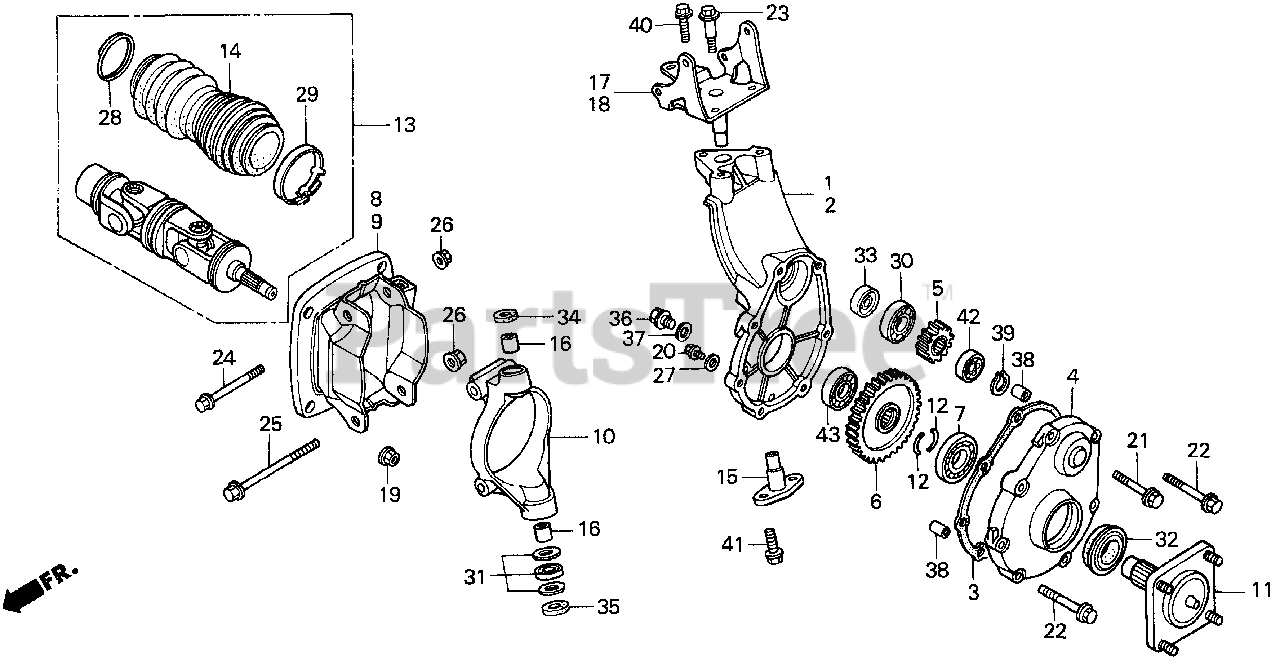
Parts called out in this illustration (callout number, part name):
1	CASE, R. RR. FINAL REDUCTION
2	CASE, L. RR. FINAL REDUCTION
3	GASKET, FINAL REDUCTION
4	COVER, FINAL REDUCTION
5	GEAR, FINAL DRIVE (12T)
6	GEAR, FINAL DRIVEN (35T)
7	BEARING, RADIAL BALL SPECIAL (6206)
8	TUBE, R. RR. AXLE
9	TUBE, L. RR. AXLE
10	HOLDER, FINAL REDUCTION CASE
11	SHAFT, AXLE
12	KEY, AXLE SHAFT LOCK
13	JOINT ASSY., RR. DRIVE
14	BOOT, RR. JOINT
15	KINGPIN (LOWER)
16	BUSH, KINGPIN
17	ARM, R. RR. KNUCKLE
18	ARM, L. RR. KNUCKLE
19	NUT, SELF-LOCK (10MM)
20	BOLT, SEALING (8MM)
21	BOLT, UBS (8X36)
22	BOLT, KNOCK (8X46)
23	BOLT, KNOCK (10X32)
24	BOLT, FLANGE (12X105)
25	BOLT, FLANGE (12X125)
26	NUT, SELF-LOCK (12MM) (SATO RASHI)
27	WASHER (8MM)
28	CLIP (50.7)
30	BEARING, RADIAL BALL (62/22)
31	BEARING, THRUST (17X30X9)
32	SEAL, WATER (32X52X11) (NOK)
32	SEAL, WATER (32X52X10.5) (NOK)
33	OIL SEAL (24X42X7) (ARAI)
34	OIL SEAL (22X35X8)
35	OIL SEAL (25X38X8)
36	BOLT, DRAIN PLUG (14MM)
37	WASHER, DRAIN PLUG (14MM)
38	PIN A, DOWEL (10X16)
39	CIRCLIP (OUTER) (17MM)
40	BOLT, FLANGE (10X25)
41	BOLT, FLANGE (10X28)
42	BEARING, RADIAL BALL (6203)
43	BEARING, RADIAL BALL (6205)
